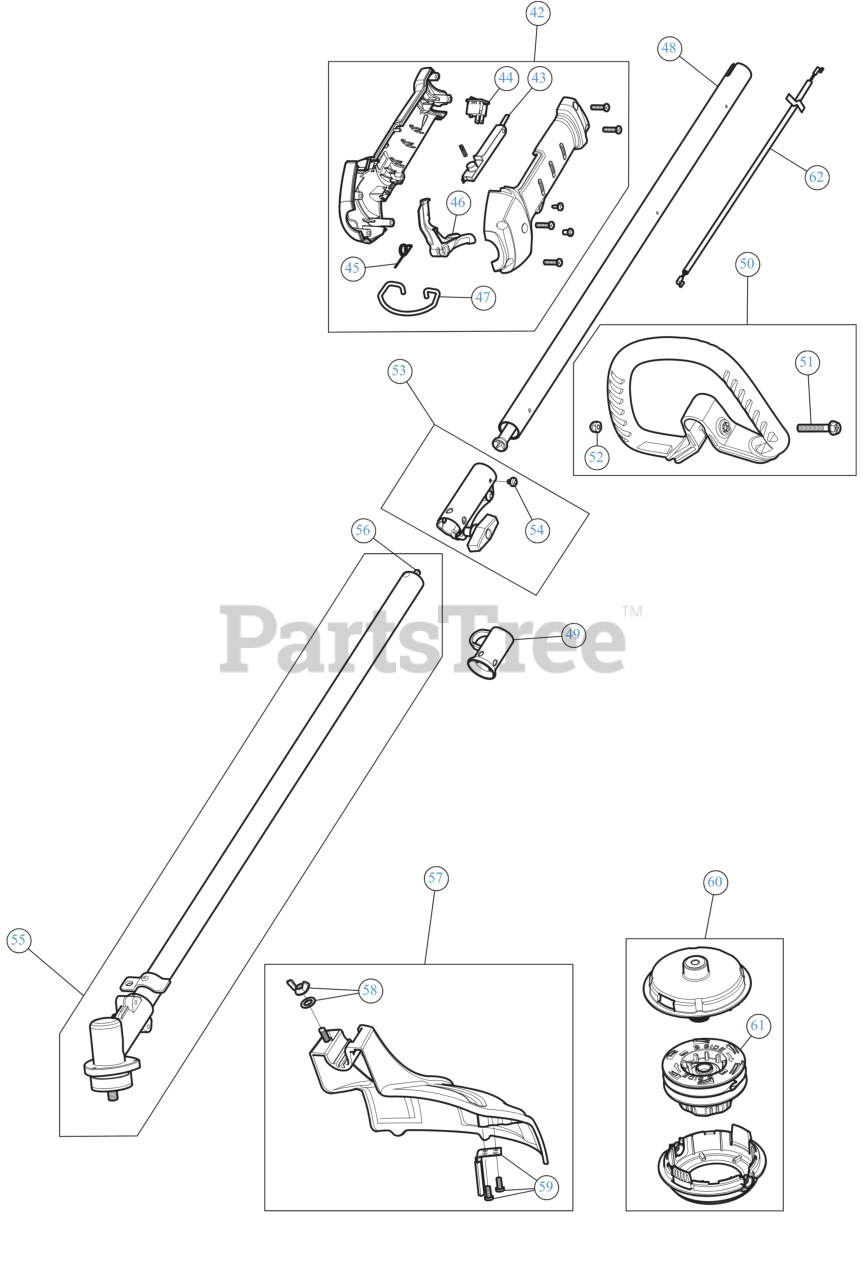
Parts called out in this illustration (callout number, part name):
42	THROTTLE GRIP ASM
43	LEVER LOCK OUT
44	SW, MOMENTARY ON/O
45	SPRING TRIG
46	THROTTLE TRIGGER
47	SHOULDER STRAP CLIP
48	DRIVE SHAFT ASSEMBLY UP
49	HANGER
50	HANDLE ASSEMBLY
51	BOLT 1/4-20X1 1/2
52	NUT 1/4-20 NYLOC
53	COUPLER ASSEMBLY
54	SCREW, 10-32X.250 TA
55	BOOM (W/GEARBOX)
56	LOWER DRIVE SHAFT
57	GUARD/BLADE ASM
58	BLADE GUARD MOUNTING HARDWARE
59	BLADE ASSEMBLY W/HDW
60	COMPLETE HEAD ASSEMBLY
61	BUMP KNOB
62	THROTTLE CABLE
